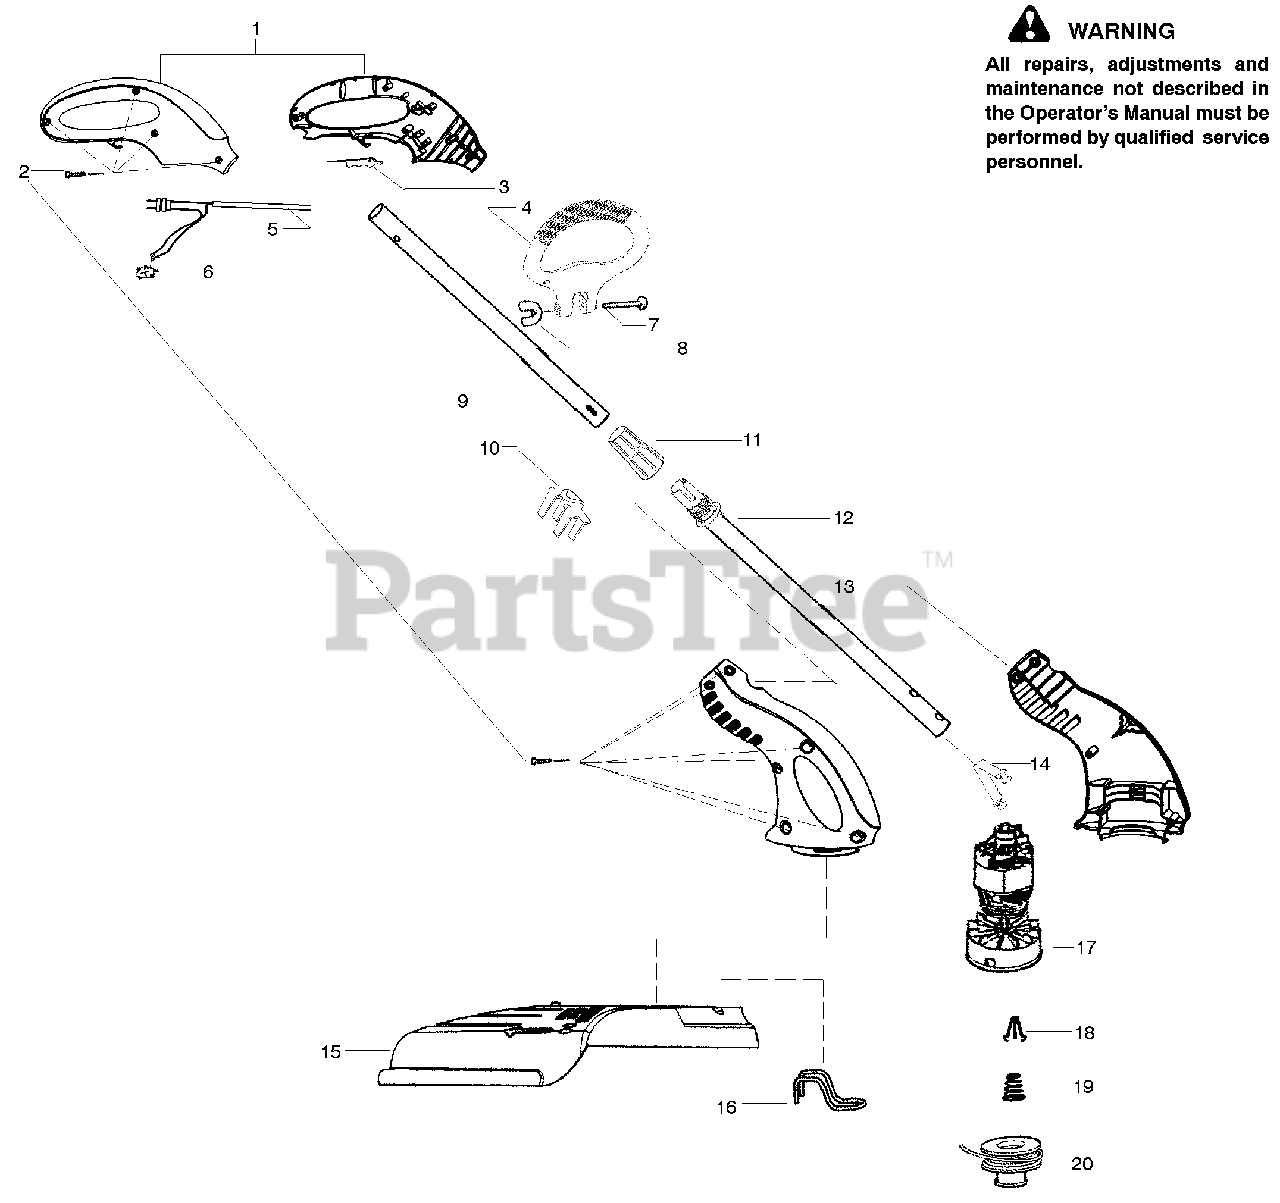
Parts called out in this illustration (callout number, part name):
1	Handle Set
2	Screw (10 pcs.)
4	Assy-Assist Handle
5	Wire Harness
7	Bolt-Carriage
8	Wingnut
9	Assy-Upper Tube
10	Button-Push
11	Nut-Collett
12	Assy-Lower Tube
13	Housing Set
14	Button-Snap
15	Shield Ass'y.
16	Guide - Edging
17	Assy.-Motor/Hub
18	Retainer-Spool
19	Spring-Return
20	Accy-W/E Spool (TNG 5)
